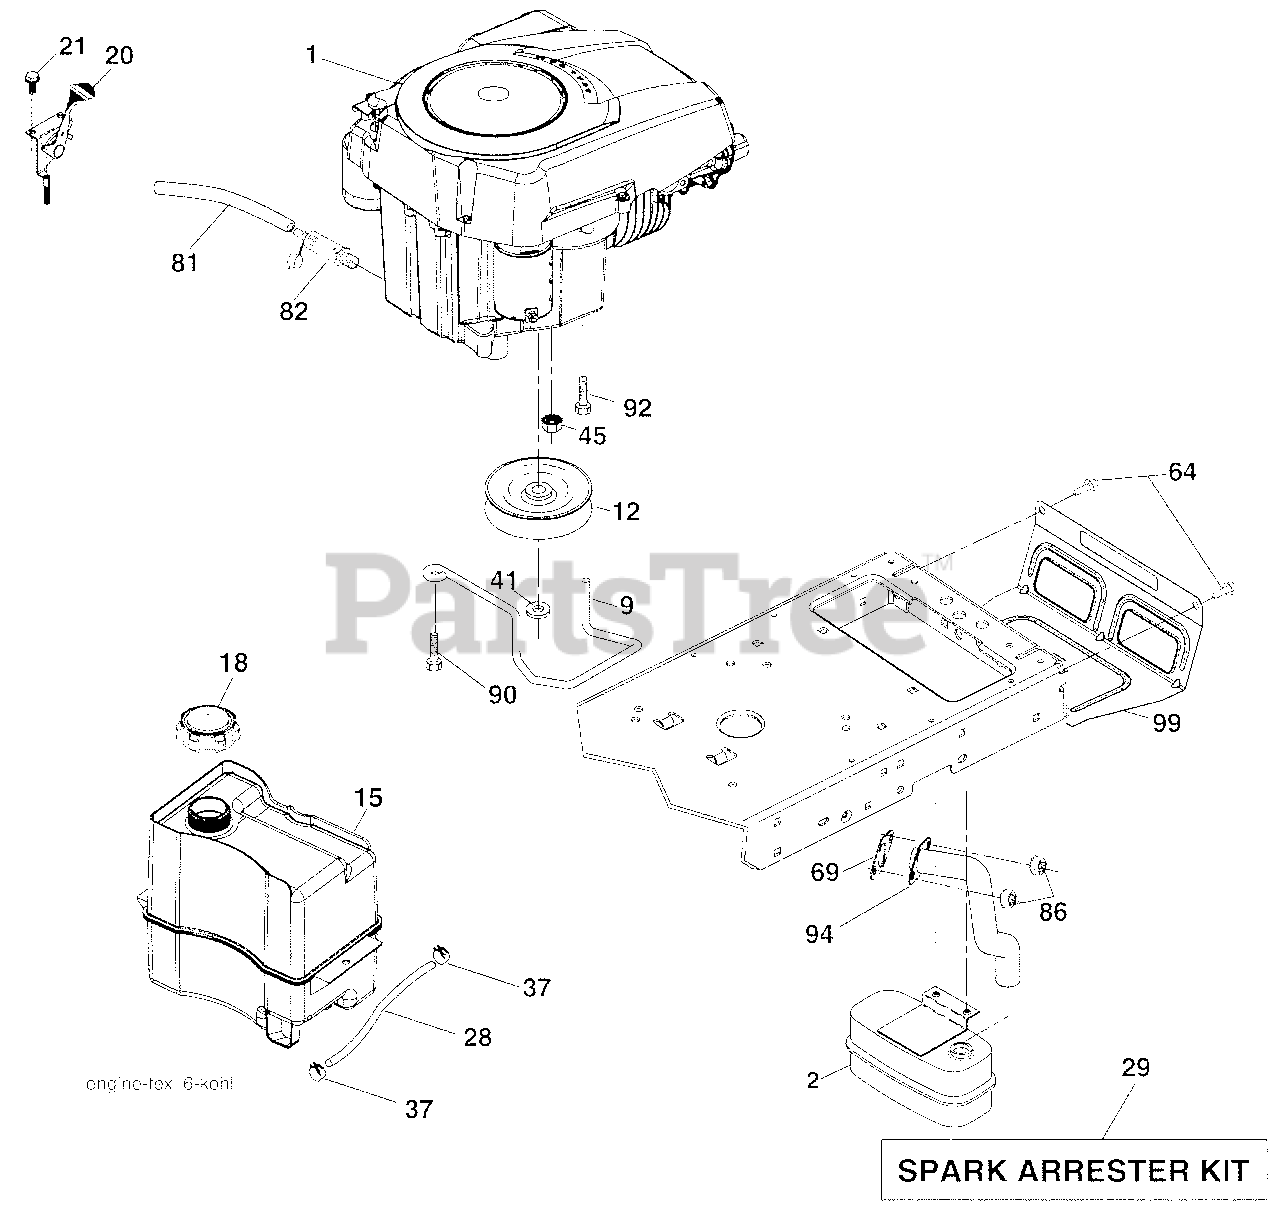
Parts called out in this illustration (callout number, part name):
9	Keeper Belt Engine
12	Pulley Engine
15	Tank Fuel 4.0
18	Cap Asm
20	Control Throttle
21	Screw 10 x 3/4 Single Lead-Hex
28	Fuel Line
29	Spark Arrester Kit
37	Clamp Hose
42	Washer Lock 7/16
43	Bolt Hex 7/16-20 x 4 Gr. 5
45	Nut Keps Hex 1/4-20 unc
64	Screw Hexwsh Thdrol 3/8-16 x 3/4
69	Gasket
81	Tube Drain Oil Easy
82	Plug Drain Oil
83	Bolt 5/16-18 unc x 3/4 w/Sems
92	Screw 3/8-16 x 1
94	Tube Exhaust
99	Shield Browning/Debris
